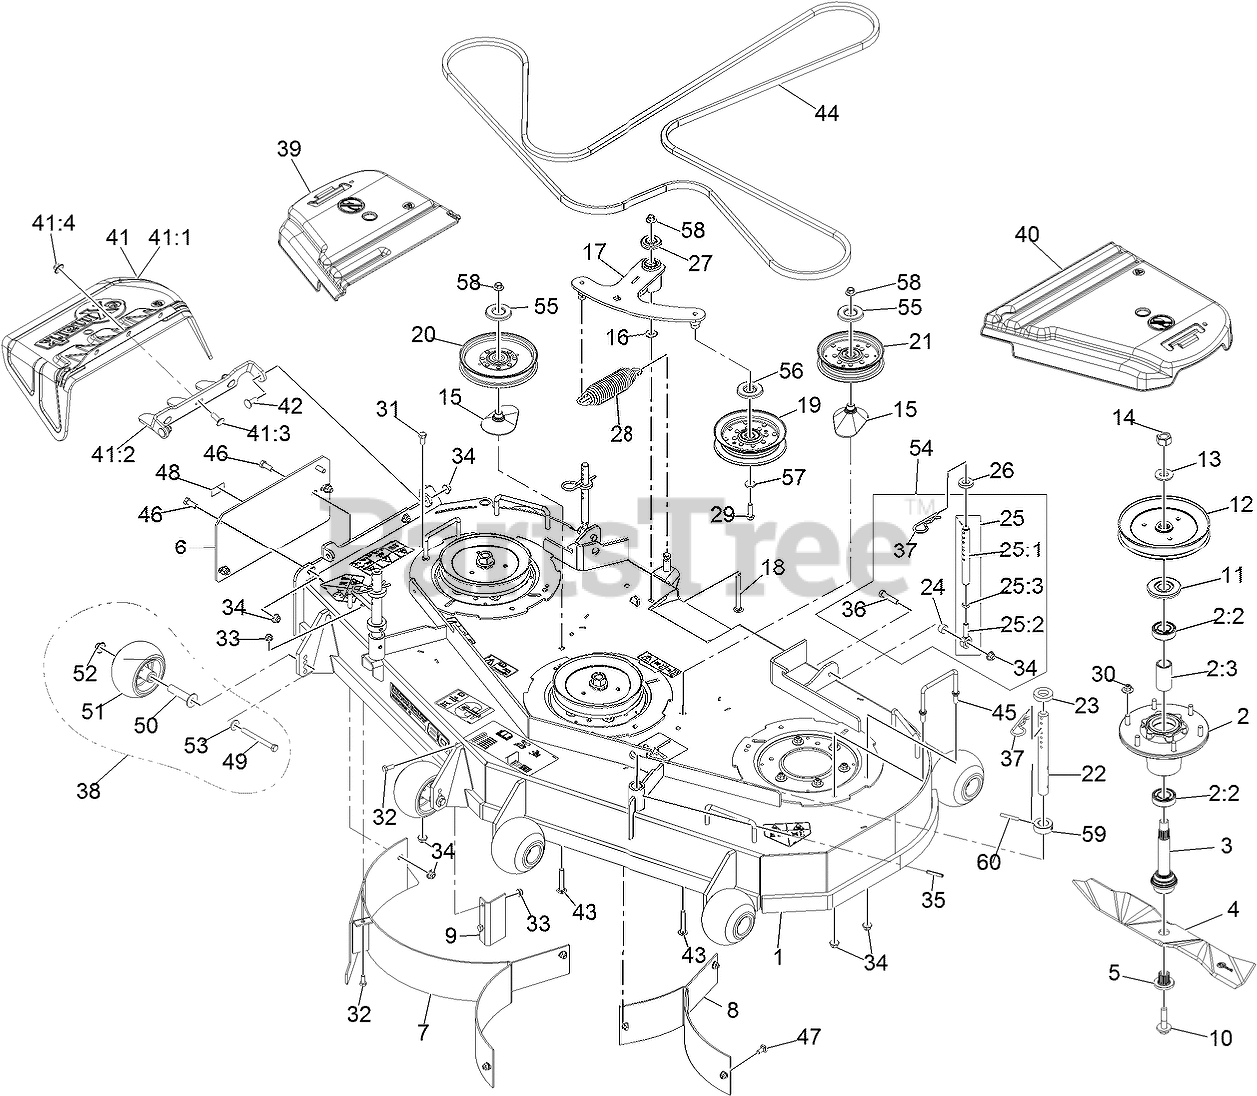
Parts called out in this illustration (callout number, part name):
1	ASM, DECK W/ DECALS, 60"
2	ASM-CUTTER HSG WITH BEARINGS
2:2	BEARING-BALL
2:3	SPACER-BEARING
3	ASM-SPINDLE AND SEAL
4	Blade-Extreme 2, 20.50"
5	BUSHING,SPLINED
6	PLATE-MULCH COVER, 604
7	BAFFLE WLD RH MULCH
8	XREF 1-632948-03 (EXMARK)
9	BAFFLE,BLOCKER MK604
10	SCREW,SEMS 1/2-20 X 2.19
11	GUARD,BEARING TOP .989
12	SHEAVE,BLADE DRIVE 7.25
14	NUT-HEX
15	SPACER-PULLEY
16	WASHER-FLAT
17	ASM, DECK IDLER
18	SCREW-CARR
19	IDLER-PULLEY, FLAT
20	IDLER-PULLEY
21	PULLEY-IDLER, FLAT
22	Rod, Deck Support
23	SPACER-DECK SUPPORT
25:1	LINK,SUPPORT
25:2	BALLJOINT
25:3	NUT-HJ
27	GUARD-TOP
28	SPRING-EXTENSION
29	SCREW-HH
30	Nut-Nyloc 3/8-16 Flg
31	SCREW-HH
32	SCREW-HH
33	NUT-HF, NI
34	NUT-HF, NI
36	SCREW-HH
37	PIN,HAIR COTTER
38	KIT, ANTI-SCALP ROLLER
39	COVER-BELT, RH
40	COVER-BELT, LH
41	ASM,DISCHARGE CHUTE
41:1	CHUTE,DISCHARGE
41:2	BRACKET,DISCHARGE CHUTE
41:3	SCREW-CARR
41:4	Nut-Nyloc 3/8-16 Flg
42	SCREW-CARR
43	BOLT-CARR, SHORT NECK
44	BELT, DECK DRIVE
45	WIREFORM-COVER
46	SCREW-HH
47	BOLT-CARR
48	Decal-Patent Ttco.Com
49	SCREW-HH 3/8-16 X 3 3/4 GR 8
50	AXLE, ROLLER
51	ROLLER-SCALP, ANTI
52	Nut-Nyloc 3/8-16 Flg
53	WASHER-BELLEVILLE
54	KIT,SUPPORT LINK W/PIN
55	SHIELD-DUST
56	SHIELD-GUARD, DUST
59	Collar, Deck Height Pin
60	PIN-ROLL
